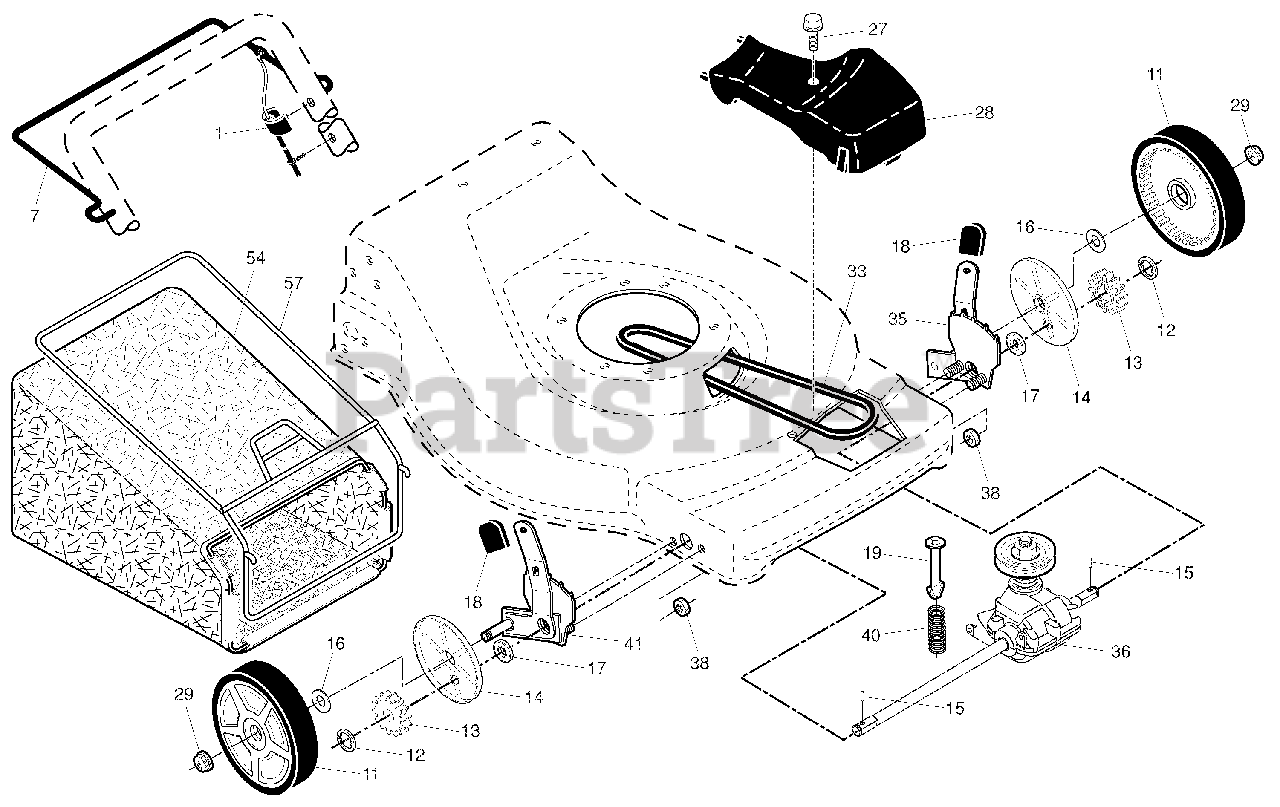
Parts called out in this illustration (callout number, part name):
1	CABLE, DRIVE CONTROL
7	Control Bar, Drive
11	WHEEL AND TIRE ASSEMBLY-FRONT
14	Dust Cover
15	Pawl, Drive
16	Washer, Flat 3/8
17	WHEEL BEARING
18	Selector Knob
19	Retainer, Spring
27	Pan Head Tapping Screw #10-24
28	DRIVE COVER
29	Nut, Hex
33	DRIVE BELT
35	KIT,WHEEL ADJUSTER, RH (INCLUD
36	Gear Case Assembly, Complete
38	Locknut, Hex 1/4-20
41	KIT,WHEEL ADJUSTER, RH (INCLUD
57	BAG FRAME
